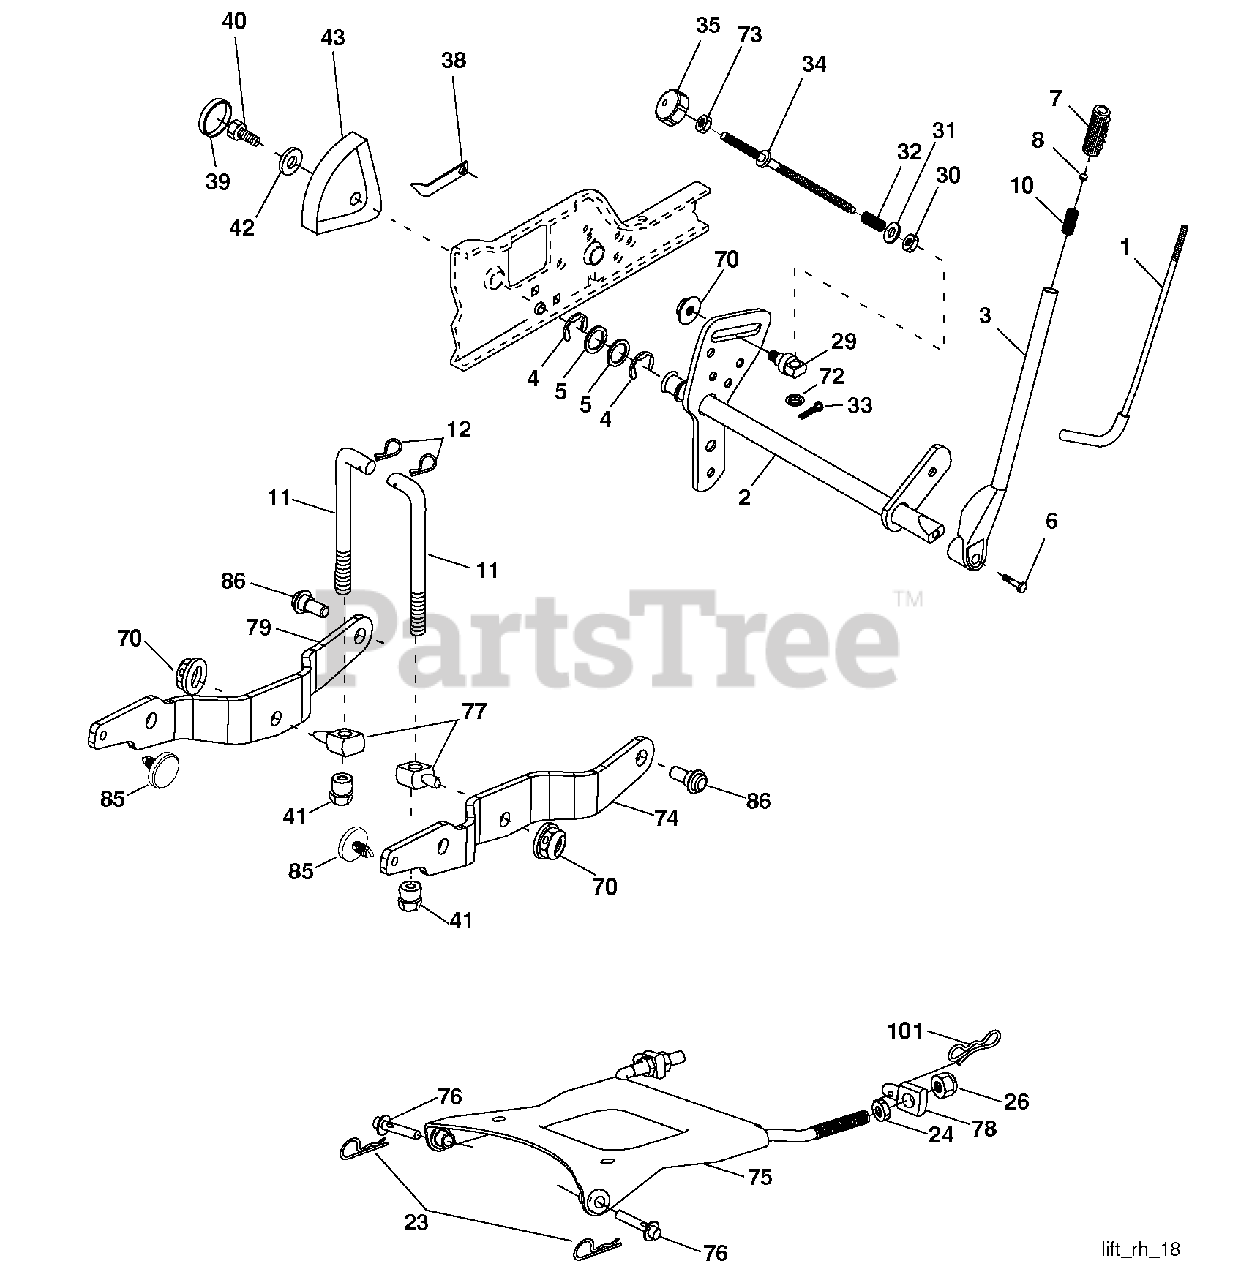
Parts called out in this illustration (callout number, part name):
1	Rod Asm., Lever
2	Shaft Asm., Lift Vgt
3	Lever Asm., Lift Rh
4	E-Ring Truarc #5133-87
5	Washer 29/32 x 1-1/4 x 16 Ga.
6	Bolt, Fin Hex 3/8-16 x 1-1/2
7	Grip, Handle
8	Button, Plunger
10	Spring 0.62 OD x 2.125
11	Link Lift
12	Retainer, Spring
23	Retainer, Spring
24	Nut, Jam Hex 1/2-13 unc
26	Nut, Lock 1/2-13 unc
29	Trunnion Inf. Height
30	Nut, Special
31	Washer 13/32 x 5/8 x 16 Ga.
32	Spring, Compression Inf Hgt
33	Pin, Cotter 3/32 x 1/2
34	Rod, Adj Lift
35	Knob, Inf 3/8-16 unc
38	Pointer, Height Indicator
39	Plug, Hole
40	Screw 5/16-18 x 3/4
41	Nut, Lift Link 7/16-20
42	Washer 11/32 x 1-1/2 x 10 Ga.
43	Scale, Indicator Height
70	Nut, Hexfl ange Lock
72	Nut, Push Phos & Oil
73	Nut Hex Jam 3/8-16 unc
74	Arm Susp. Rear RH
75	Plate Asm Susp. Front
76	Pin Flange
77	Trunnion Susp. Arm
78	Trunnion Susp. Front
79	Arm Susp. Rear LH
85	Insert Wear
86	Bolt Shoulder
101	Pin Cotter 7/16 Bow Tie Lock
